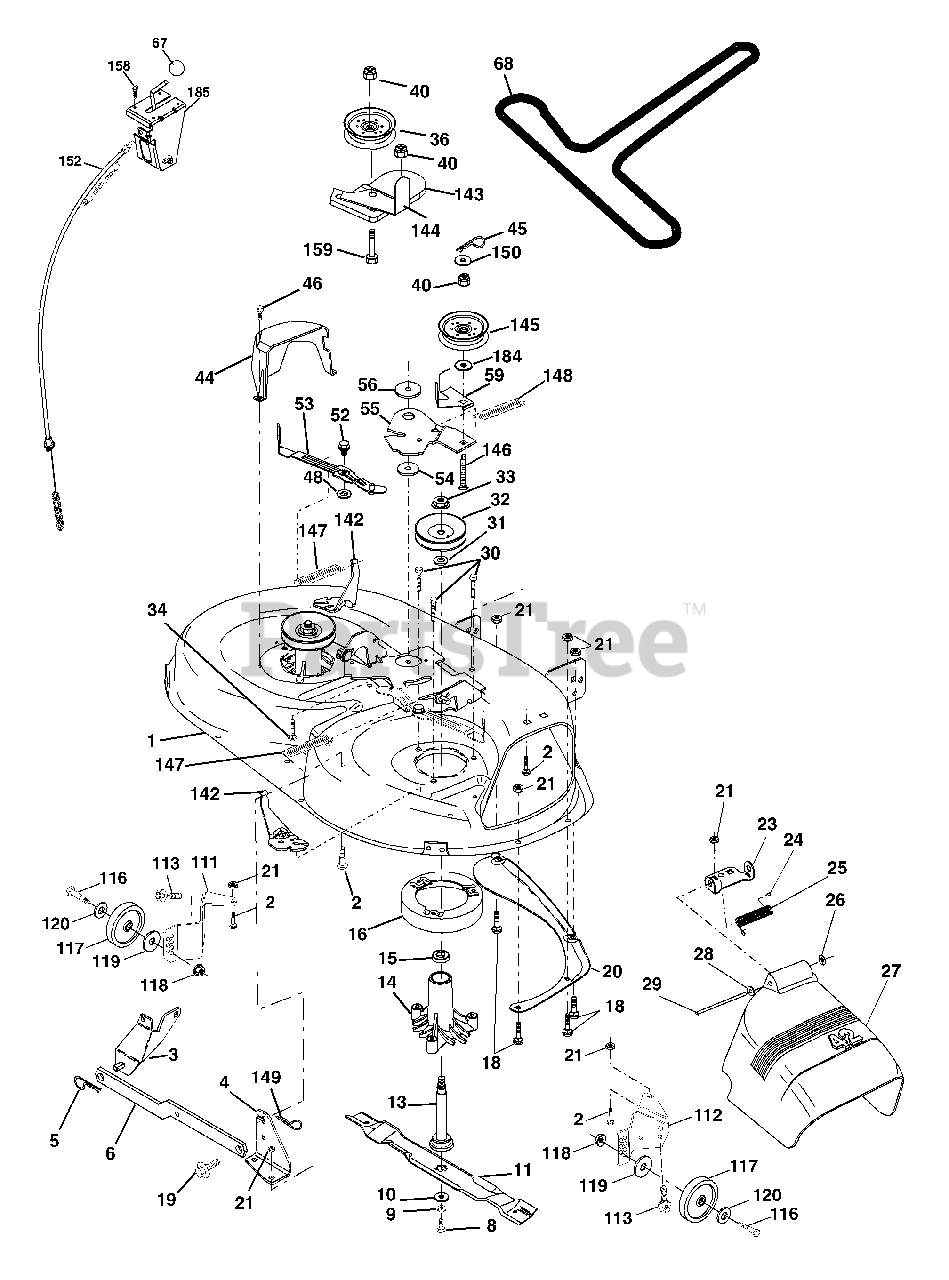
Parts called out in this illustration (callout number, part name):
1	Mower Deck Assembly, 42"
2	Bolt
3	Bracket Asm Fr. Sway Bar 3/42
4	Bracket Asm Deck 42" Sway Bar
5	Retainer Spring
6	Bar Sway Deck
8	Bolt 3/8-24 x 25 Gr. 8 patched
9	Washer, Lock
10	Washer, Hardened
11	Blade, 42" Mulching Std
11	Blade, 42" Mulching Premium
11	Blade, 42" Hi-Lift
13	Shaft Assembly, Mandrel, Vented
14	Housing, Mandrel, Vented
15	Bearing, Ball, Mandrel
16	Stripper, Mandrel Deck
18	Bolt, Carriage 5/16-18 x 5/8
19	Bolt, Shoulder
20	Baffle, Vortex
21	Nut
23	Bracket, Deflector Mower 42"
24	Cap, Sleeve 80 x 112 Blk Mower
25	Spring, Torsion, Deflector 2 52
26	Nut, Push Phos & Oil
27	Shield, Deflector 42" Blk
28	Washer 11/32 x 5/8 x 16 Ga.
29	Rod, Hinge 42" 6 75 W/G
30	Screw Thdrol Washer Head
31	Washer, Spacer Mower Vented
32	Pulley, Mandrel
33	Nut, Toplock 9/16 Flange
34	Bolt
36	Pulley, Idler, Flat
37	Washer 13/32 x 13/16 x 16 Ga.
44	Guard, Mandrel, LH
45	Retainer
46	Screw, Thdrol 1/4-20 x 5/8 T
48	Washer, Hardened
52	Bolt, Shoulder 5/16-18 unc
53	Arm Assembly, Pad, Brake
54	Washer, Hardened
55	Arm, Idler
56	Spacer, Retainer
59	Guard TUV Idler
67	Knob
68	V-Belt, 42" Mower
111	Bracket Wheel Guage LH
112	Bracket Wheel Gauge RH
113	Bolt Rdhd Sqnk 5/16-18 unc x 3/4
116	Bolt Shoulder
117	Wheel Guage
118	Nut Centerlock 3/8-16 unc
119	Washer 17/32 x 15/16 x 12 Ga.
120	Washer 3/8 x 7/8 x 14 Ga.
142	Arm Spring Brake Mower
143	Bracket Arm Idler 42"
144	Keeper Belt 42" Clutch Cable
145	Pulley Idler Flat
146	Bolt Carriage Idler
147	Spring Extension
148	Spring Return Idler
149	Retainer Spring Yellow
150	Washer 9/32 x 3/4 x 10 Ga.
152	Clutch Cable 42"
158	Screw Hex Thd Cut 1/4-20 x 1/2
159	Bolt Rdhd Sqn 3/8-16 unc x 1-3/4
184	Washer 13/32 x 7/8 x 10 Ga.
185	Head Asm Cable Clutch
